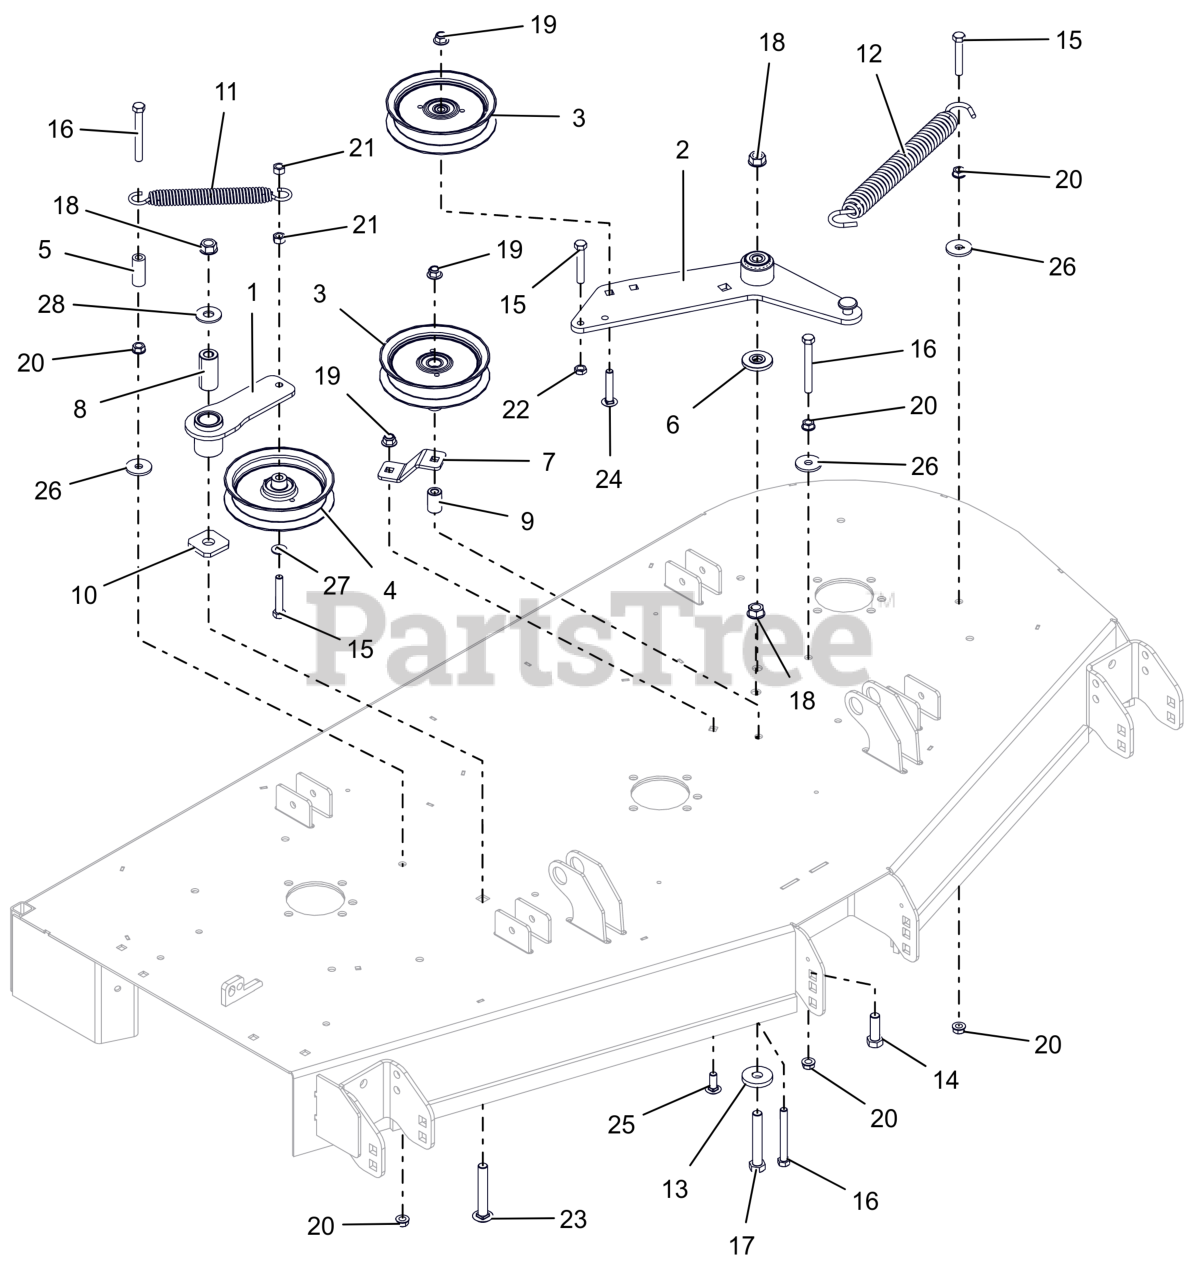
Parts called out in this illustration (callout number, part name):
1	ASM, IDLER ARM (DECK)
2	ASSEMBLY, MAIN BELT IDLER
3	IDLER, FLAT 5.00"
4	IDLER, FLAT 5.00"
5	HOSE, .38 X 1.65
6	SPACER, IDLER ARM
7	PTO FIXED IDLER MTG BRKT-ORG
8	BSHG, SPCR .502X.997X2.03 PM
9	BUSHING, SLV .380X.750X1.190
10	WSHR-FLT .640X1.75X.250
11	SPRING, EXTENSION
12	SPRING, EXTENSION
13	WSHR-FL-STL 0.557X1.625X0.25 ZCC
14	BLT,HEX .50-13X1.50 G5 ZCC
15	BLT,HEX .38-16X2.25 G5 ZCC
16	BLT, HEX .38-16X3.25 G5 ZCC
17	BLT,HEX .50-13X3.25 G5 ZCC
18	NUT-LK-CTR-FLG .500-13 GG ZCC
19	NUT,NYL-FLG .38-16 GF ZCC
20	NUT, SPNLK-FLG .38-16 G5 ZCC
21	NUT-LK-CTR .38-16 ZC120
22	NUT-JAM .375-16 G2 ZCC
23	BTL,RHSSN .500-13 X 3.25 G5 ZCC
24	BLT,RHSSN.375-16X2.00 G5 ZCC
25	BLT,RHSSN .38-16X1.00 G5 ZCC
26	WSHR,FLT .406X1.375X.135 ZCC
27	WSHR,FLT .406X.812X.065 ZCC
28	WSHR,FLT .563X1.375X.109 ZCC
